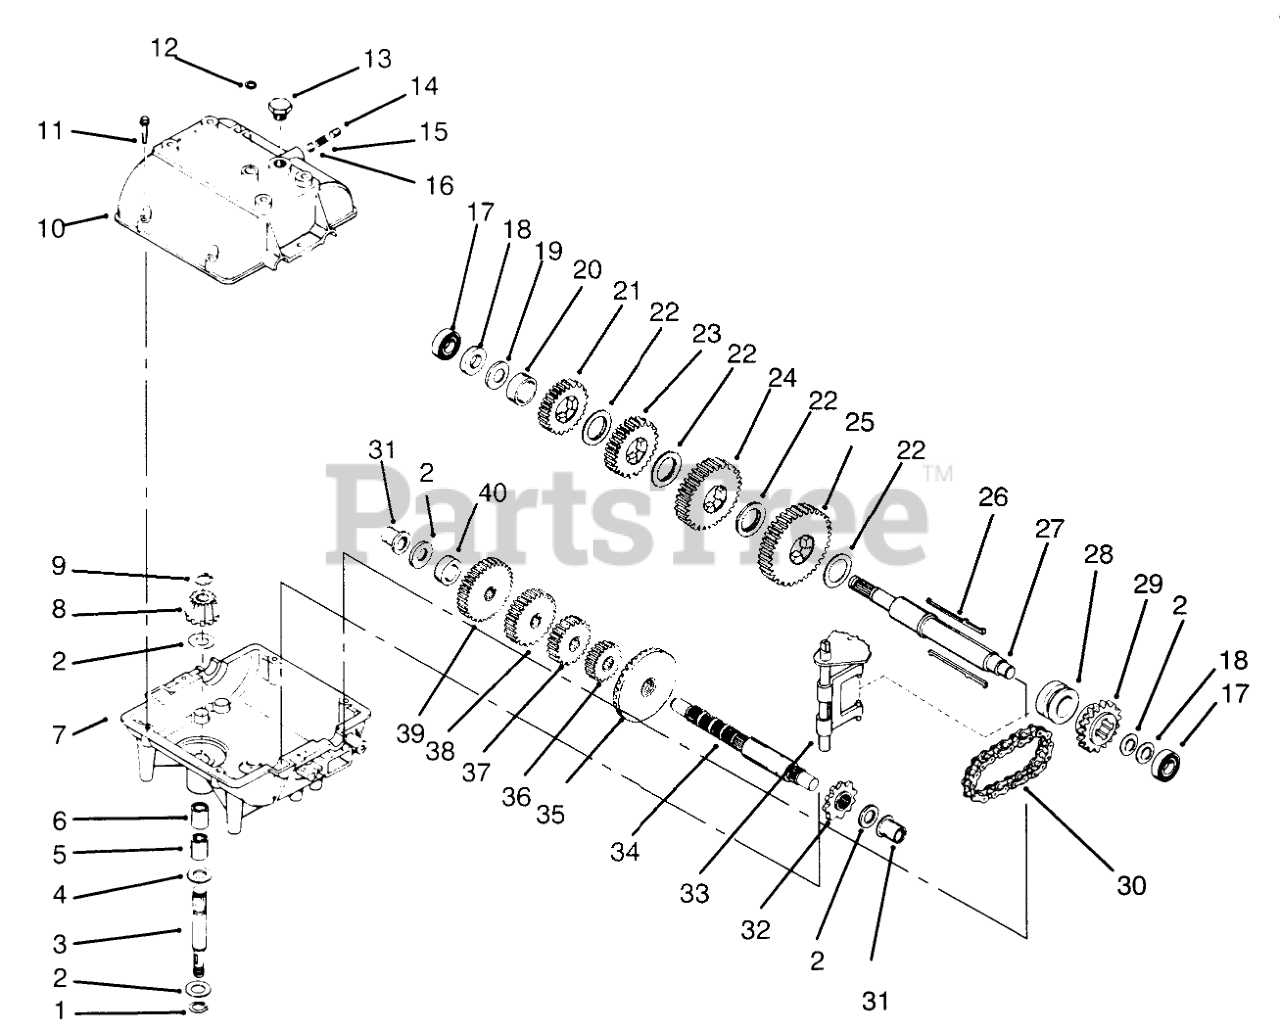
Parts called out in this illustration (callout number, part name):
1	Ring-Snap
2	Washer
3	Shaft-Input
4	O Ring
5	Bearing-Needle
6	Bearing-Needle
7	Case-Transmission
8	Bevel Pinion-Input
9	Ring-Retainer
10	Cover-Transmission
11	Ring Set (.020 O S)
12	Cut Seal-Square
14	Screw-Set
15	Spring
16	Ball-Steel
17	Bearing-Ball
18	Thrust Washer
19	Washer
20	Spacer
21	Gear-Spur, 25 Teeth
22	Washer
23	Gear-Spur 27 Teeth
24	Gear-Spur, 30 Teeth
25	Gear-Spur, 35 Teeth
27	Shaft-Output/Brake
28	Collar-Shift
29	Sprocket-18 Teeth
30	Chain-Roller #41
31	Bushing-Flange
32	Sprocket-9 Teeth
33	Rod and Fork ASM
34	Countershaft
35	Gear-Bevel, 42 teeth
36	Gear-Spur 15 Teeth
37	Gear-Spur, 20 Teeth
38	Gear-Spur 23 Teeth
39	Gear-Spur, 25 Teeth
40	Spacer
